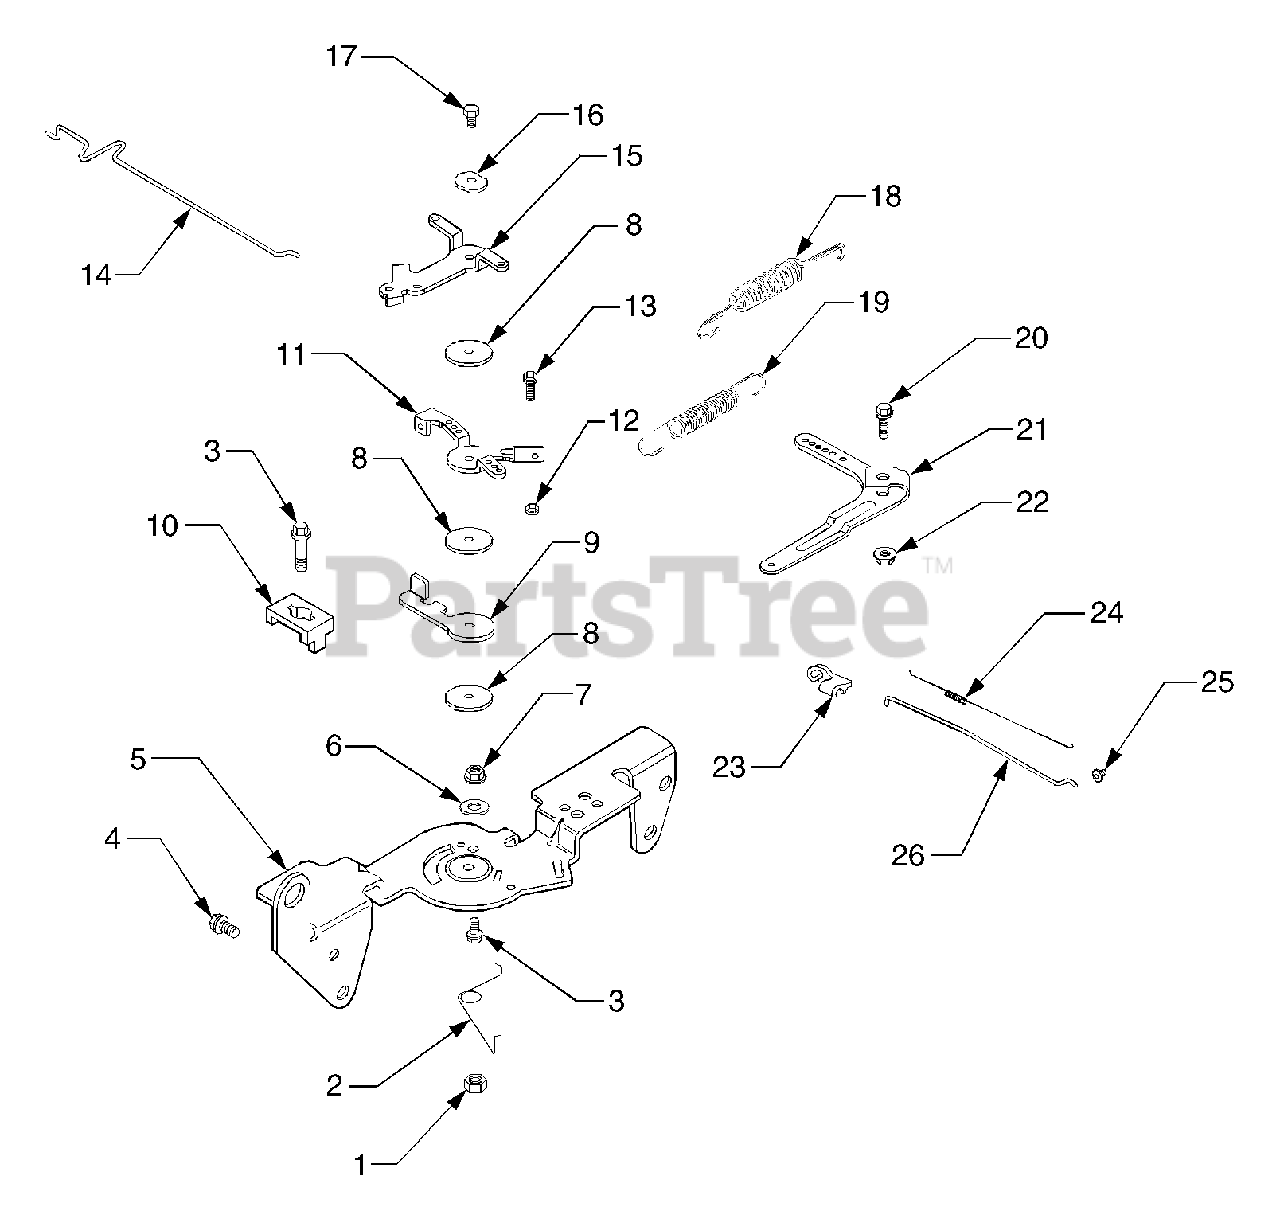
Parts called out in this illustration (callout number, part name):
1	Nut, Hex Lock M5 x 0.8
2	Spring, Choke Return
3	Screw, Hex Flange M5 x 0.8 x 16
4	Screw, Hex Flange M6 x 1.0 x 16
5	Bracket, Control
6	Washer, Lock
7	Nut, Hex Flange
8	Washer , Plain 5.5mm
9	Lever, Throttle Actuator
10	Clamp, Cable
11	Lever, Throttle Control
12	Nut, Hex M4 x 0.7
13	Screw, Hex Cap M4 x 0.7 x30
14	Linkage, Choke
15	Lever, Choke
16	Washer, Spring 1/4"
17	Screw, Hex Flange M5 x 0,.8 x 20
18	Spring, Throttle Limiter
19	Spring, Governor
20	Screw, Round Hd. Square Neck
21	Lever, Governor
22	Nut, Hex Flange M6 x 1.0
23	Bushing, Linkage Retaining
24	Spring, Linkage
25	Bushing, Linkage Retaining
26	Linkage, Throttle
